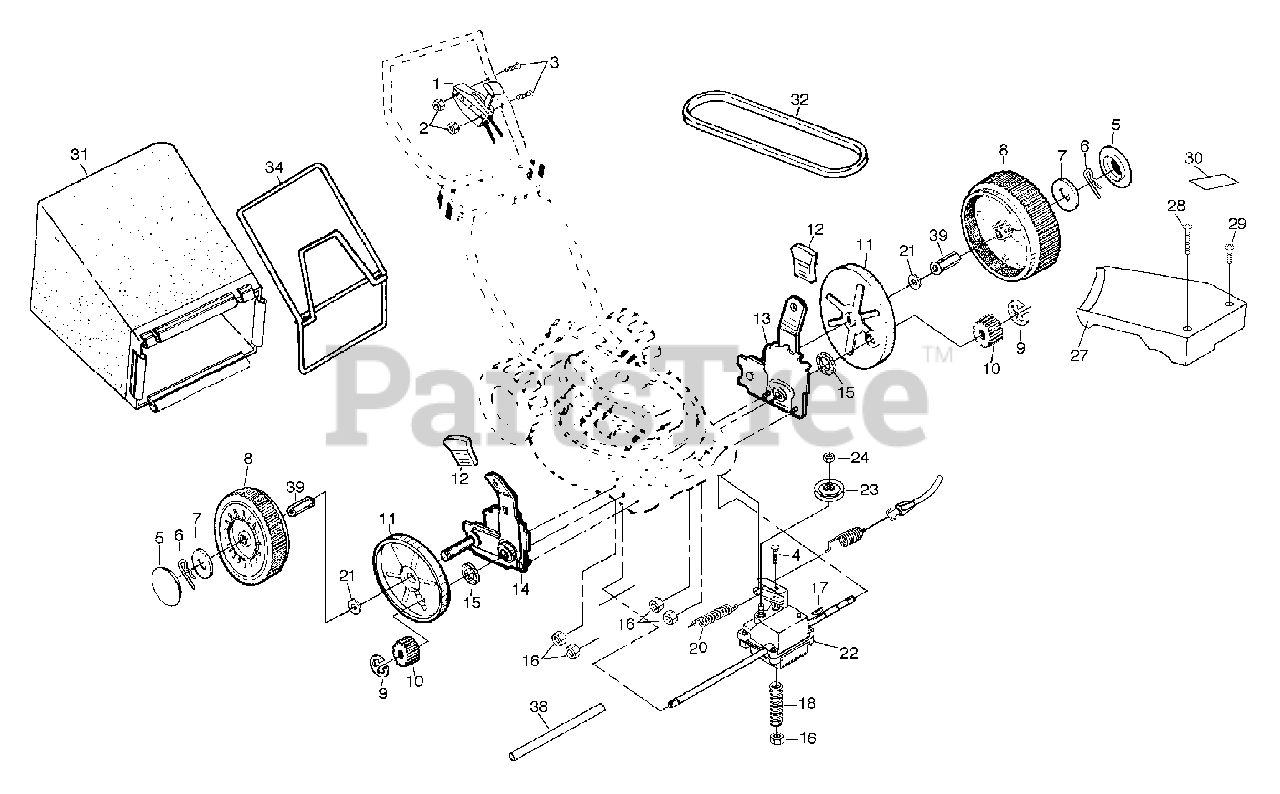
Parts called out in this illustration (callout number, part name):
1	Drive Control
2	Locknut #10-24
3	Hex Head Screw 1/4-20 x 1-1/8
4	Carriage Bolt 1/4-20 x 2
6	Retainer Clip
8	Wheel & Tire Assembly
11	Dust Cover
12	Selector Knob
13	Wheel Adjuster Assembly (Left)
14	Wheel Adjuster Assembly (Right)
15	Felt Washer
16	Locknut
17	Hi-Pro Key
22	Gear Case Assembly
23	Drive Pulley
24	Locknut
27	Drive Cover
28	Pan Head Machine Screw #10-24 x 2-3/4
29	Pan Head Machine Screw #10-24 x 1-3/4
30	Drive Cover Decal
32	V-Belt
34	Frame Grass Bag 2-1/2
35	Grass Bag 2-1/2 Soft
38	Drive Shaft Cover
39	Wheel Bushing
